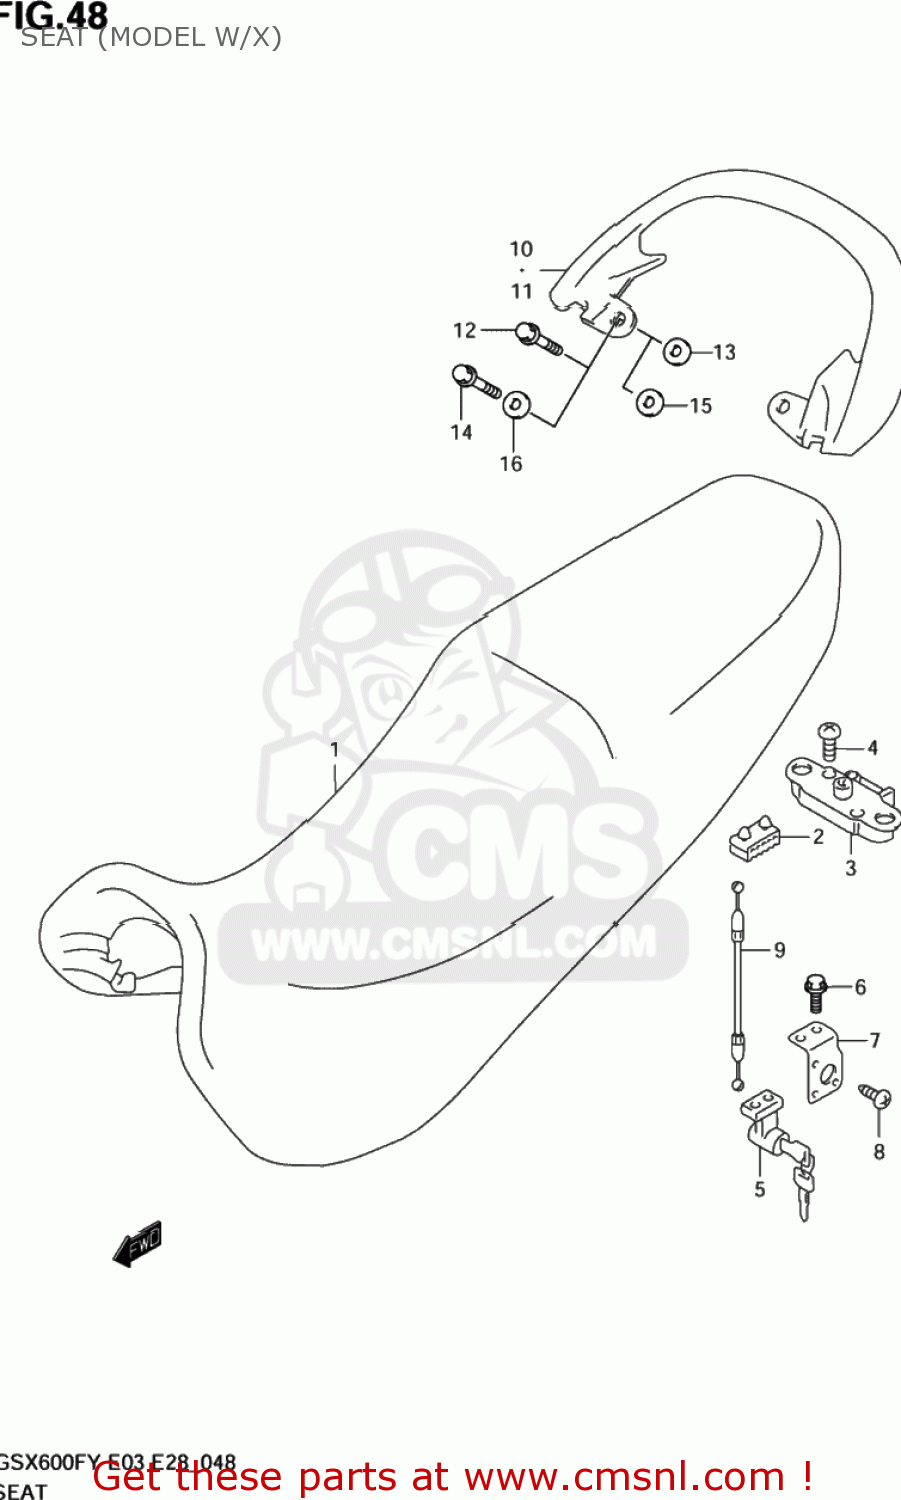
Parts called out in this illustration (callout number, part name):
1	SEAT ASSEMBLY
2	CUSHION,SEAT(40X20X15)
3	BRACKET,SEAT SUPPORT,RIGHT
4	SCREW
5	LOCK SET,SEAT
6	BOLT
7	BRACKET,SEAT LOCK
8	SCREW
9	CABLE,SEAT LOCK
10	HANDLE,PILLION RIDER
11	HANDLE,PILLION RIDER(RED)
12	BOLT
13	CUSHION
14	BOLT
15	CUSHION,RIDER HNDL(17X24X1.5)
16	WASHER(8.5X24X2.3)
